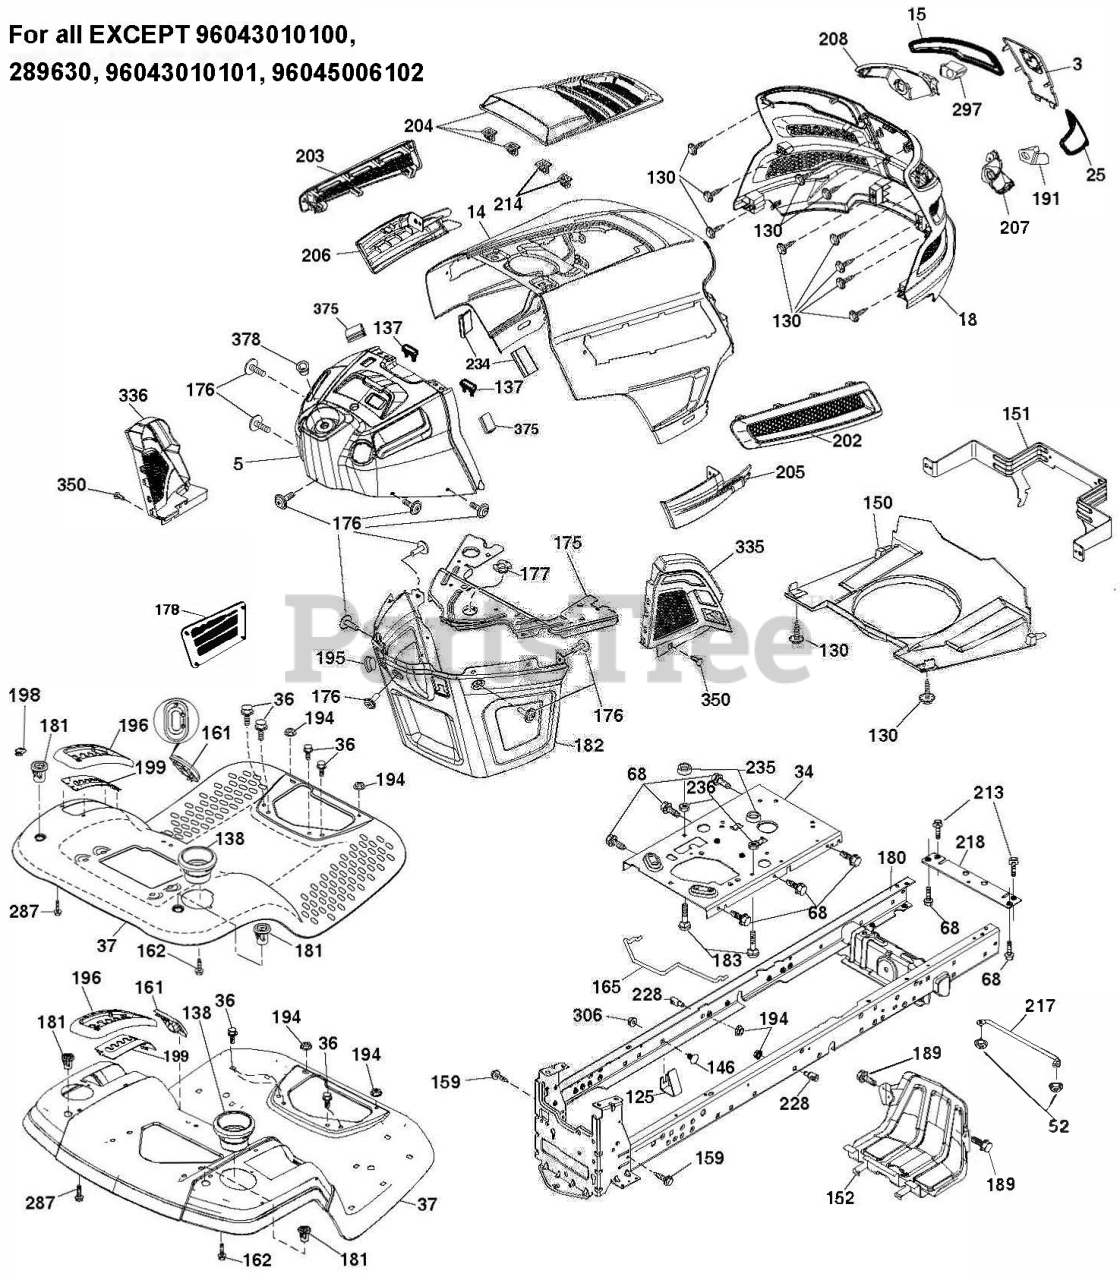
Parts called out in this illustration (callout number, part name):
3	APPLIQUE.SUBASM.GT.HUSQ.II
5	DASHBOARD.UPPER.ASM.GT2.X498
5	DASH.ASM.W/BUMPERS.READYSTART
14	HOOD.ASM.HUSQVARNA.GT.TEX.ORAN
15	LENS.HEADLIGHT.LH.GTII.2011
18	GRILLE SUBASM.GT.II.LOW.HDLGHT
18	Grilles
25	LENS.HEADLIGHT.RH.GTII.2011
34	PLATE.ENGINE.WELDED.CHASSIS
36	SCREW 5/16"
37	FENDER.TLT.W/CPH.W/FW.ORANGE
37	FENDER.TLT.PDL.CNTRL.W/CPH.ORG
37	FENDER.ERGO.LT.W/CPH.W/FW.ORNG
125	CLIP.FUEL.LINE
130	SCREW.#10 X 0.750.BOS
130	Screws
137	BUMPER DASH
138	HOLDER.CUP.LT.GREY
146	BOLT.RDHD.SHT.SQNK.3/8-16X5/8
150	AIR.DUCT.GTV.BLACK
151	BRACKET.PIVOT.HOOD.GT.HUSQ.II
152	SHIELD.BROWNING.PNT.GT.V2
159	SCREW, 3/8-16X3/4
161	WINDOW.FUEL.LT.HUSQ.TEX.498
162	Screws
162	SCREW.HI-LO.CONSOLE
165	SUPPORT.TANK.REAR.W/TEX
175	PLATE.PNT.CROSSMEMBER.HUSQ/PRE
176	SCREW.#10-24X5/8.RN.QU
177	BUSHING STEERING
177	BUSHING, STEERING
178	CARGO.ASM.NET.TXGT.W/C
180	CHASSIS
181	BUSHING.MNT.FEND.CRGO.TEX.49
182	DASH.LOWER.COMMON.12V.ADAPTOR
183	Screws
183	BOLT.5/16-18X1-1/4 FULL THD
189	BOLT.HEX.HD.WASHER.5/16-18X.75
189	SCREW
189	SCREW, 3/8-16X3/4
191	INSERT.REFLECTIVE.RH.HUSQ.GTII
194	GSPW Nuts
194	NUT LOCK HEX FLANGE 5/16-18
195	PLUG.HOLE.DASH.LOWER.12V.BLK
196	DECKLFT.CONSOL FULL ASSM GREY
198	BUSHING.MNT.FEND.CRGO.TEX.49
198	INDICATOR.DECK.LIFT.RED
199	PLATE.DECK.LIFT.HUSQ.LT
202	VENT.SIDE.RH.GT.HUSQ.II.
203	VENT.SIDE.LH.GT.HUSQ.II.498
204	VENT.TOP.ASM.HUSQ.GT2
205	SIDE.TRIM.RH.GT.HUSQ.II
206	SIDE.TRIM.LH.GT.HUSQ.II.GRAY
207	HEADLIGHT.CUP.BEZEL.HUS.GT2.RH
208	HEADLIGHT.CUP.BEZEL.HUS.GT2.LH
213	SCREW HEXAGON HEAD SCREW 5/16-
213	BOLT
214	CLIP.RETAINER.TINNER.
217	ROD.PIVOT.HOOD
218	X-PIECE.HOOD.STOP.NON/
228	STUD.W/"D"ANTI-ROTATION
234	BUMPER.HOOD.TEX.HUSQVARNA
235	SPACER FENDER
235	Spacers
236	NUT.CENTERLOCK.5/16-
287	SCREW 1/4X20
297	INSERT.REFLECTIVE.LH.HUSQ.GTII
306	NUT LOCK FLG 3/8-16 UNC
335	COVER.LOWER.DASH.RH.BLACK
336	COVER-LH.LOWER.DASH.GT2.BLACK
350	CLIP.X-MAS.TREE
375	BUMPER CLIP-ON. DASH 1"
378	BUSHING FLANGE; PLASTIC
